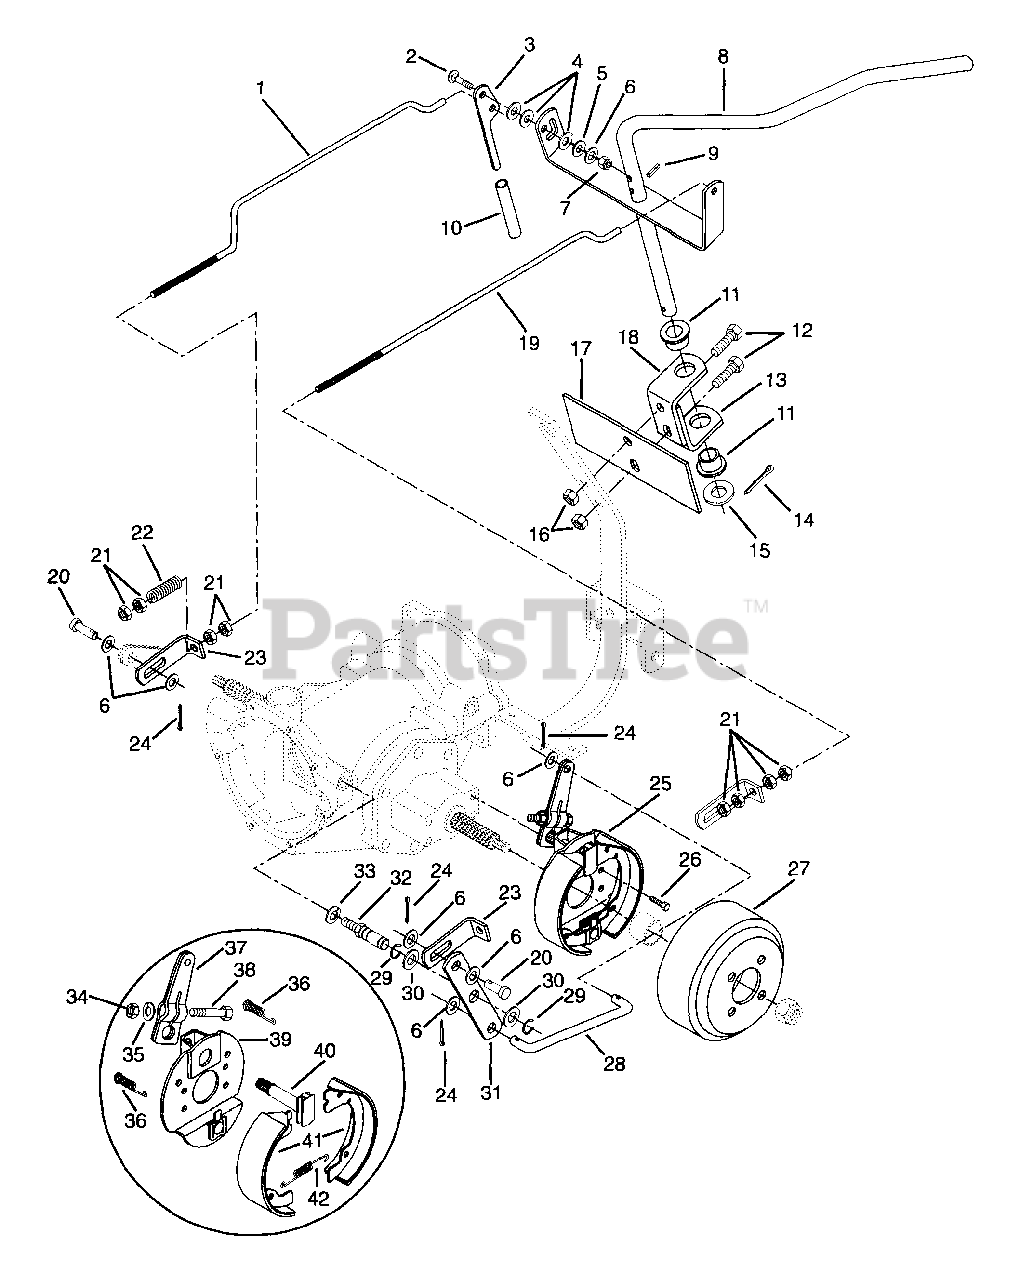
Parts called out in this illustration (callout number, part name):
1	Rod, Brake
1	Rod, Brake Right Hand
2	Bolt-Round Head Square Neck .38-16 x 1.50
3	Handle, Parking Brake
4	Washer-Flat-Nylon .375 x .75 x .060
5	Washer-Rubber .375 x .75 x .125
6	Washer-Flat-Steel .406 x .812 x .065
7	Nut-Locking-Center .375-16 Grade 2
8	Weldment, Brake Handle
9	Pin-Roll .313 x 2.00
10	Grip, Brake Handle
11	Bushing-Flange 1.082 x 1.385 x .870 x 1.750
12	Bolt-Hex .50-13 x 2.00 Grade 5
13	Bracket, Brake Handle
14	Pin-Cotter .188 x 1.50
15	Washer-Flat-Steel 1.120 x 1.500 x .092
16	Nut-Locking-Center .50-13 Grade 5
17	Plate, Instruction
18	Bracket, Brake Handle
19	Rod, Brake Left Hand
20	Pin, Clevis 3/8 x .750
21	Nut-Jam .375-16
22	Spring-Compression .105 x .61 x 2.50
23	Bracket, Adjustment
24	Pin-Cotter .09 x .75
25	Brake, 7 x 1-3/4 Mechanical
26	Bolt-Hex .380-16 x .75
27	Drum, 7 x 1-3/4
28	Rod, Brake Link
29	Ring-Retaining-External .625 x .042
30	Washer-Flat-Steel .656 x 1.312 x .095
31	Plate, Pivot
32	Stud, Pivot
33	Washer-Lock .125 Reg.
34	Nut-Jam .312-24 Grade 2
35	Washer-Lock .313 x .078
36	Spring, Shoe Ret Box
37	Arm, Cam Lever
38	Bolt-Hex .31-24 x 1.75
39	Plate, Back
40	Cam, Brake
41	Kit, Brake Shoe
42	Spring, Shoe Return
